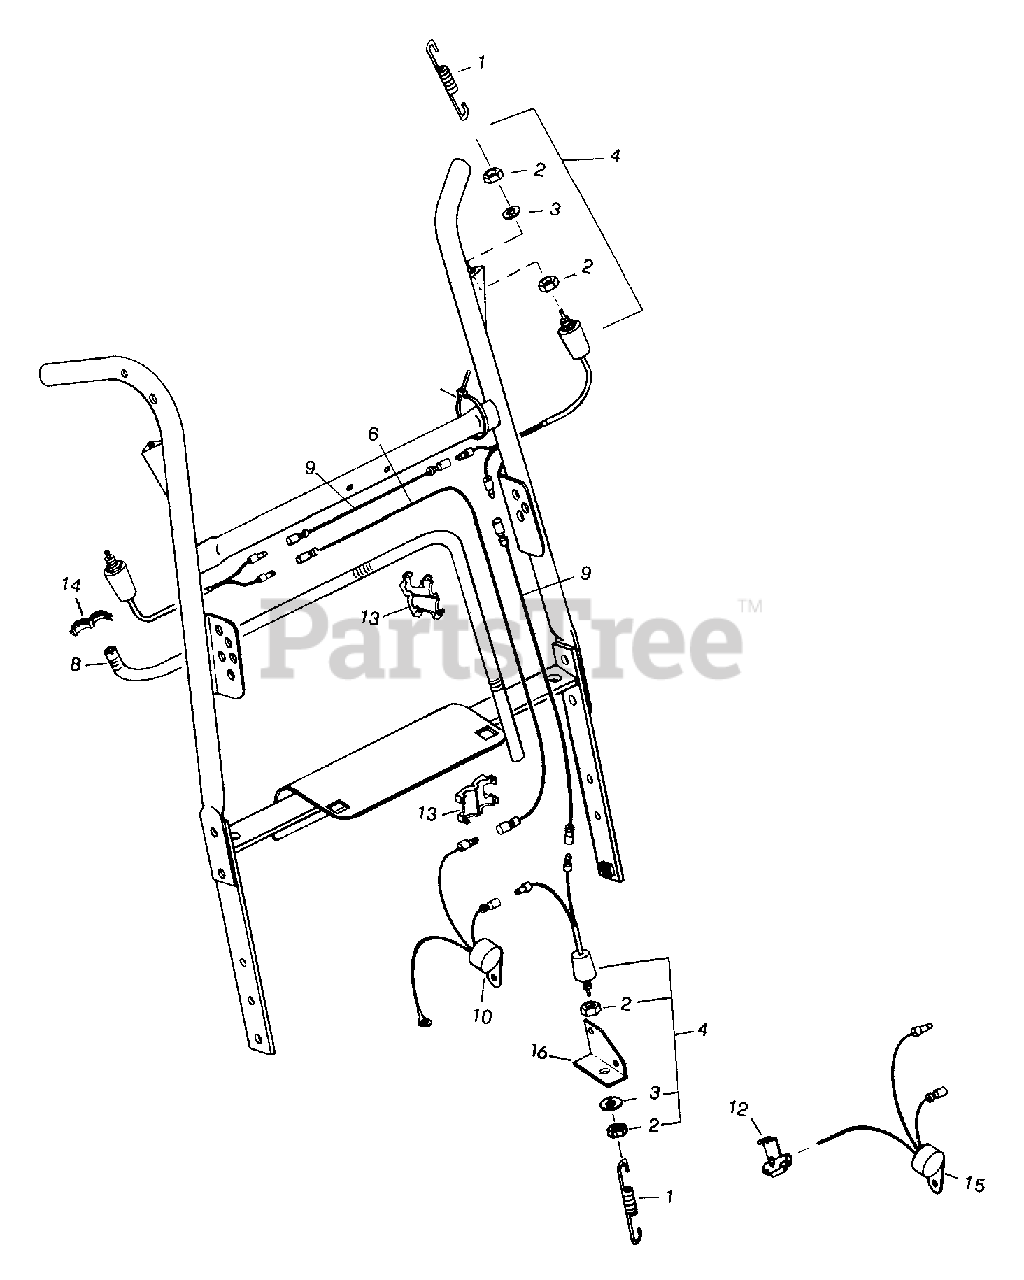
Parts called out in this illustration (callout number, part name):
1	Spring
2	M10 x .75 Hex Nut
3	Vinyl Washer
4	Interlock Switch-Complete
6	Long Interlock Wire-Complete
8	Flex Guard Loom
9	Short Interlock Wire-Complete
10	Interlock Module (Briggs & Stratton Engine Only)
12	Splice (Kawasaki Engine Only)
13	Flex Guard Outlet
14	Flex Guard Clip
15	Interlock Module (Kawasaki Engine Only)
16	Interlock Bracket
